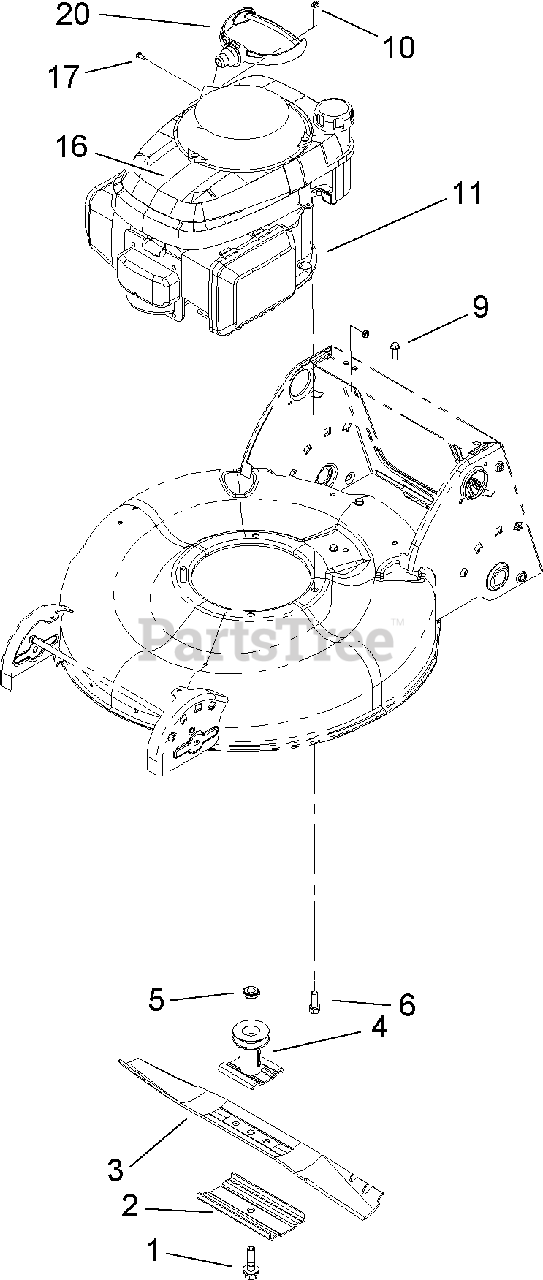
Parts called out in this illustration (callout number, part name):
1	BOLT-BLADE
2	SUPPORT-BLADE
3	BLADE-21 IN
4	BLADE DRIVER ASM
5	Spacer-Driver
6	SCREW
9	SCREW-HWH
10	STOP-ROPE
17	SCREW-METRIC
20	HANDLE-RECOIL
